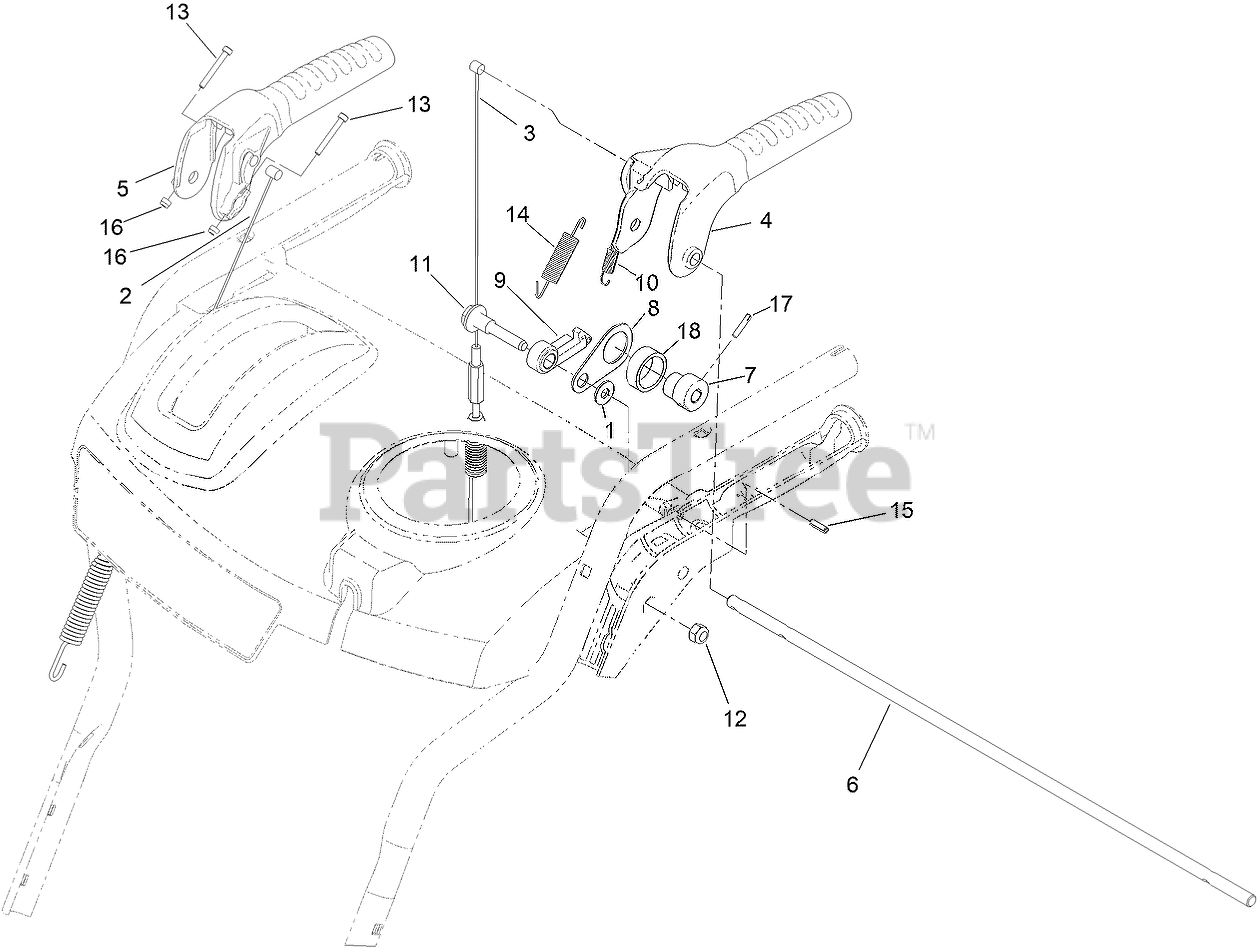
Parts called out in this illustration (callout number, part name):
1	WASHER-FLAT
2	CABLE-AUGER
3	CABLE-TRACTION
4	HANDLE-CONTROL, TRACTION
5	AUGER CONTROL ASM
6	ROD-LOCKOUT
7	CAM-LOCKOUT
8	LINK-LOCKOUT
9	LATCH-LOCKOUT
10	SPRING-LOCKOUT, HANDLE
11	SCREW-SHOULDER
12	NUT-HEX
13	SCREW-HSH
14	SPRING-RETURN, LEVER
15	PIN-ROLL, SLOTTED
16	NUT-LOCK ROHS
17	PIN-QUARTER GROOVE
18	SPACER-PLASTIC
